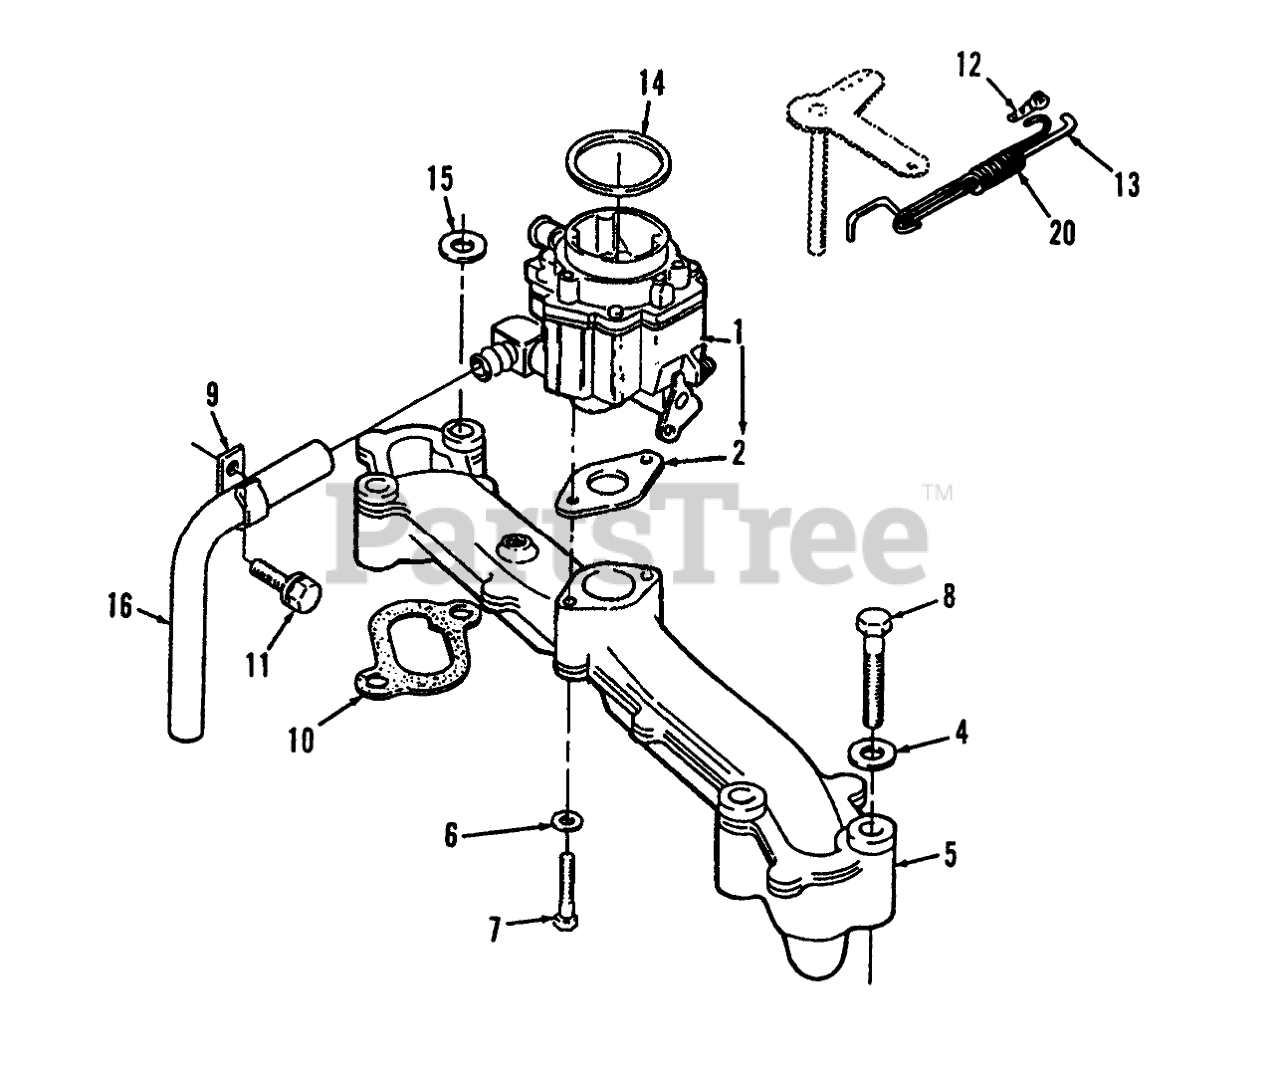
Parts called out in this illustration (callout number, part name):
1	Carburetor (Incl. Mounting Gasket, Elbow, & "O" Ring)
2	Gasket
4	WASHER-FLAT
5	MANIFOLD
6	Bolt
7	Bolt
9	Clip
10	GASKET
11	Screw
13	GOVERNOR CONTROL ROD
15	FLAT WASHER
16	FIXED-JET
20	Spring-Governor Rod
